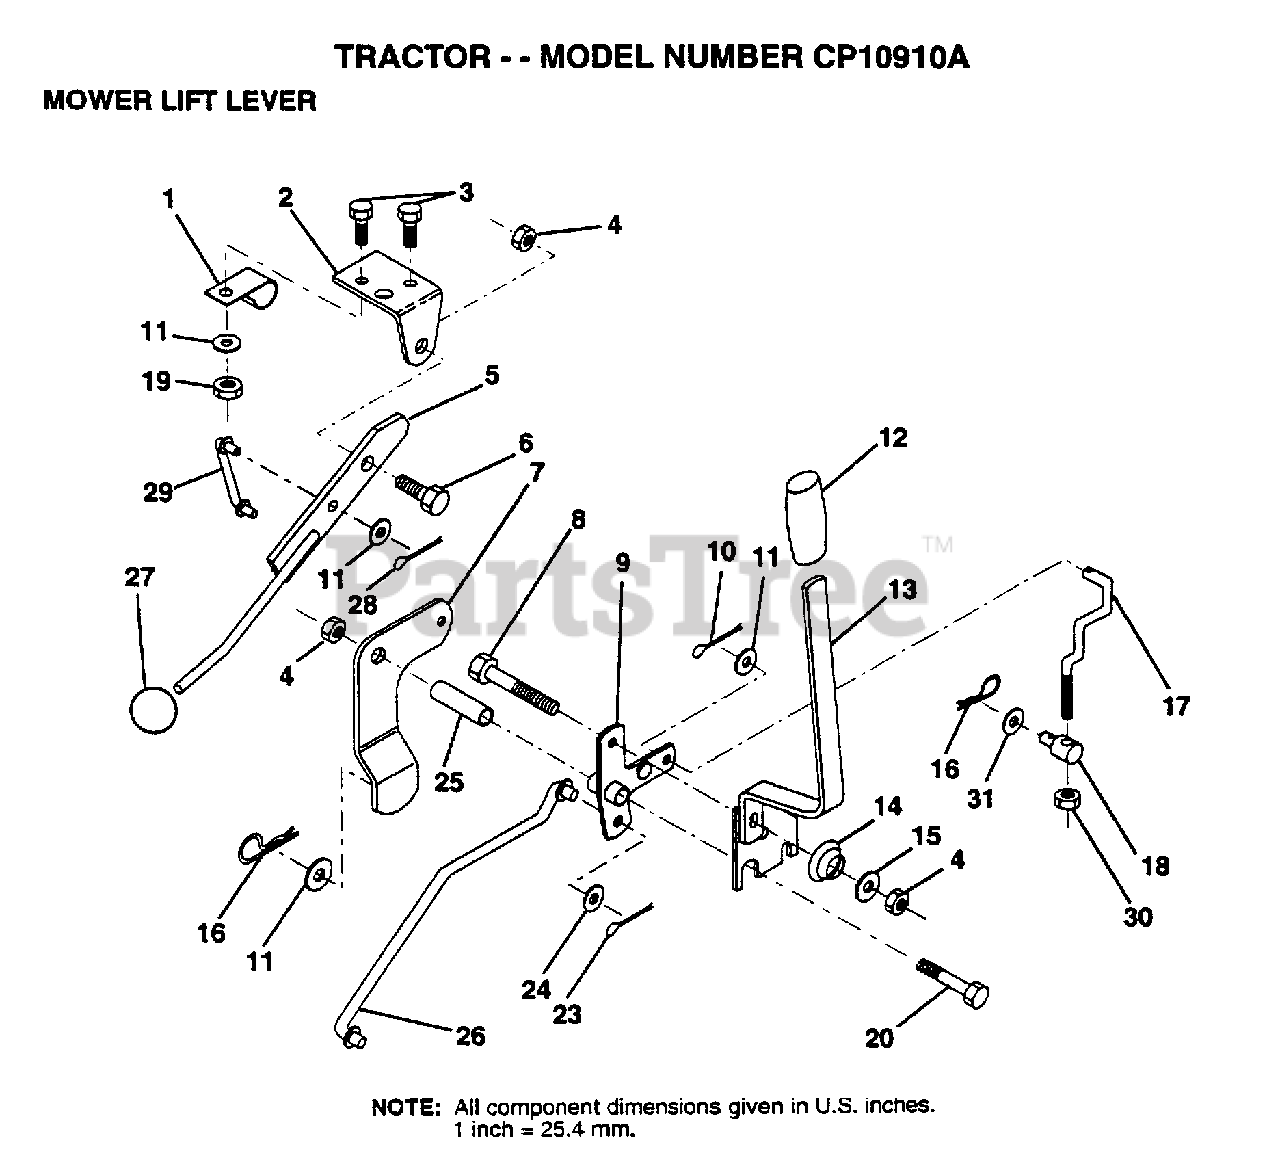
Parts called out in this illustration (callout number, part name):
1	"CLIP,INSULATOR"
2	BRKT CLUTCH
3	BOLT HXHD FIN
5	LEVER.ASM.CLUTCH
6	"BOLT, SHOULDER LT"
7	MWR CLUTCH ARM AS
8	BOLT
9	"BELLCRANK,LIFT"
10	COTTER PIN
11	WASHER
13	HANDLE.ASM.LIFT
14	SPRING COMPRESSIO
15	WASHER T
16	SPRING.RETAINER
17	"LINK,LIFT FRT"
18	TRUNION ADJ
20	BOLT
23	PIN COTTER 1/8
25	TUBE SPACER
26	ROD LIFT MOWER
27	KNOB T(3/8 HOLE)
29	CLUTCH LINK
30	NUT
31	WASHER
